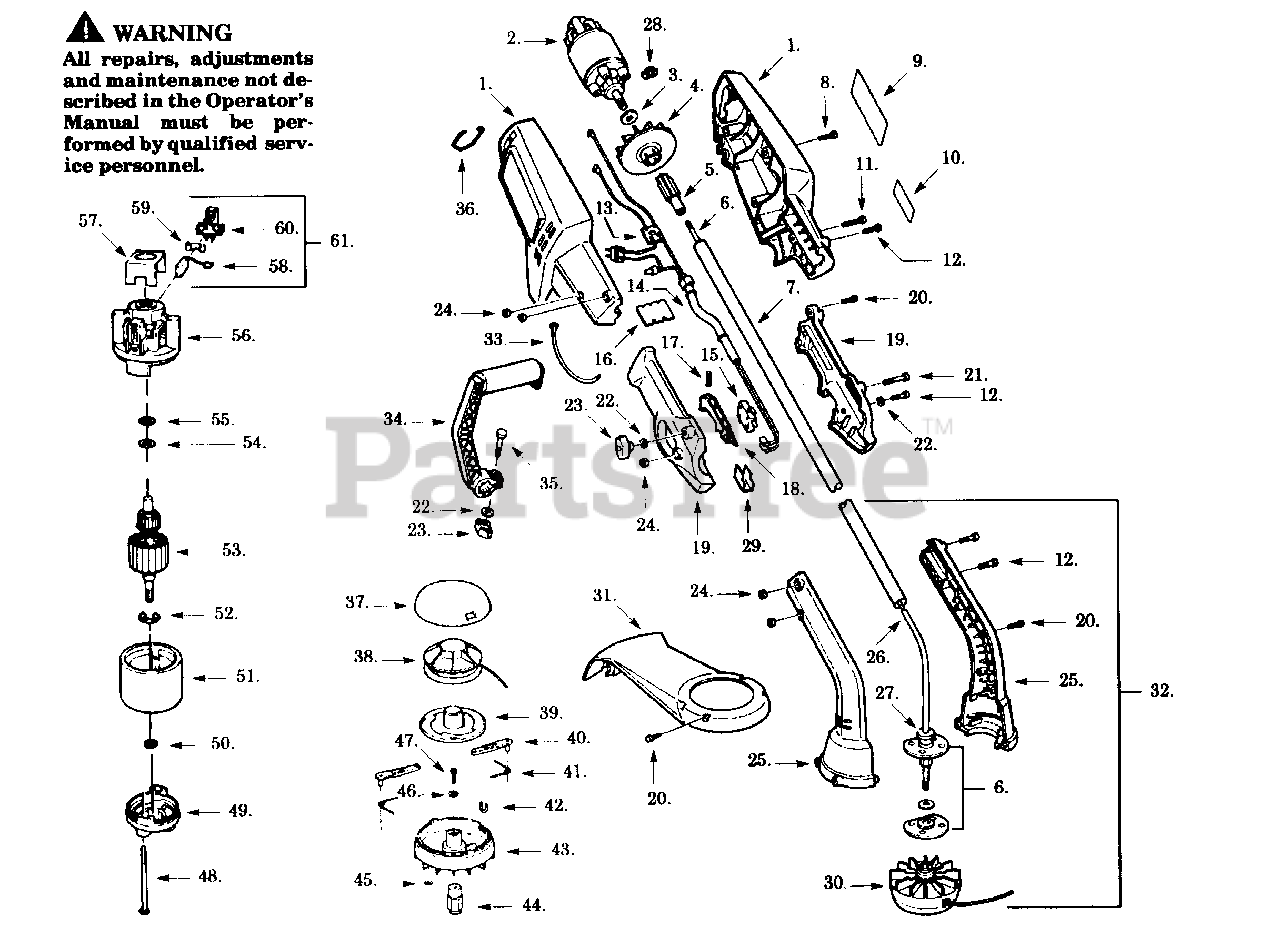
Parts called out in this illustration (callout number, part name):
1	Motor Hsg. Set
2	Motor Ass'y.
5	Shaft Adapter
6	Flex Shaft/Bearing Ass'y. Kit
7	Tube Ass'y.
9	Warning Label (Not a serviceable part)
10	Motor Hsg. Label (Not a serviceable part)
13	P.C. Bridge
14	Harness Ass'y. (Incl. 13 & 15)
16	Wire Mount Board
17	Trigger Spring
19	Trigger Hsg. Set
25	Spindle Hsg. Set
26	Tubing Sleeve
27	Felt Washer
28	Retaining Ring
29	Switch Insulator
30	Cutting Head Ass'y.
31	Guard Ass'y.
32	Spindle Head Ass'y. (Incl. 12, 20, 24-27, & 30)
33	Tie Strap
34	Handle Ass'y. (Incl. 20,22,23 & 35)
38	Spool w/Line
42	Line Shield
43	Housing Head
44	Drive Adaptor
45	Push Nut
49	Endbell Ass'y. (Drive)
51	Field Ass'y.
52	Retaining Ring
53	Armature Ass'y.
56	Endbell Ass'y. (Brush)
57	Insulator
59	Spring Brush
60	Brush Holder
61	Brush Holder Ass'y. (Incl. 58-60)
